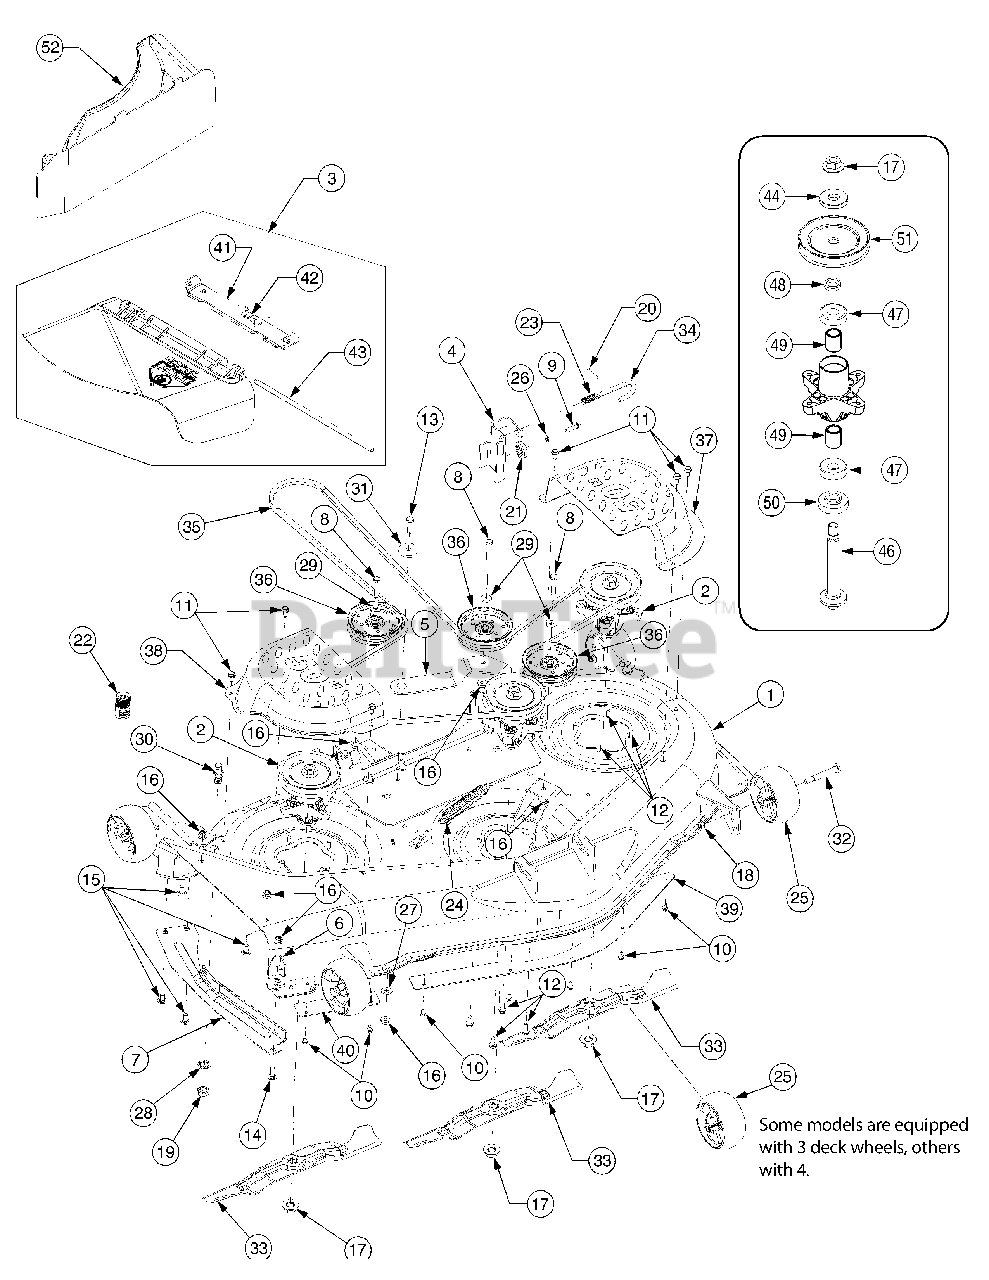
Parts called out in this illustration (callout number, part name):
1	Deck Housing
2	Spindle Assembly
3	Discharge Chute Ass’y
4	Deck Adjustment Brack w/Weld Nut
5	Idler Arm
6	Chute Stop Deflector
7	Guard, Finger
8	Hex Screw 3/8-16 x 1.75
9	Hex Bolt 5/16-18 x 1.25
10	Hex Wash S-Tapp Scr 1/4-20 x .50
11	Hex Wash HD AB Scr 5/16-12 x .75
12	Hex Wash. Hd. Scr. 5/16-18 x .75 Lg.
13	Hex Bolt 3/8-16 x 1.25
14	Carriage Bolt 3/8-16 x 1" Lg. (Gr. 5)
15	Short Neck Carriage Bolt 3/8-16 x .75
16	Flange Lock-Nut 3/8-16 Gr. F Nylon
17	Hex Flange Nut 5/8-18
18	Hex. Flanged L-Nut 3/8-16 Gr. F
19	Hex Nut M16-1.5 DIN 936
20	Cotter Pin 1/8" Dia x 1.25
21	Deck Adjustment Gear
22	Water Nozzle Adaptor
23	Comp. Spring .531 OD x 1.75 Lg.
24	Extension Spring .94 OD x 6.74
25	Deck Wheel 5.0
26	L-Wash 5/16 ID
27	Cupped Washer .45 x 1.0 x .062
28	L-Washer Internal
29	Flat Washer .38 x .93 x .11
31	Shoulder Spacer .884 x .190
32	Shoulder Screw, 1/2 Diameter x 2.5
33	Blade 17.9" Lg.
34	Deck Release Pin
35	V-Belt Type A Sec x 134
36	Idler Pulley w/Flange 4.25 Dia
37	LH Belt Cover
38	RH Belt Cover
39	Deck Skirt Center
41	Chute Mounting Bracket
42	Torsion Spring
44	Flat Washer .76 ID x 1.5 OD x .12
45	Grease Fitting
46	Spindle Shaft 5.75 Lg.
47	Ball Bearing 20 x 47 x 14:6204:DS
48	Spacer .79 x 1.25 x .175
49	Spacer .080 x 1.10 x 1.322" Lg.
50	Spacer .79 x 1.82 x .55
51	V-Type Pulley, 5.29
52	Mulching Plug
